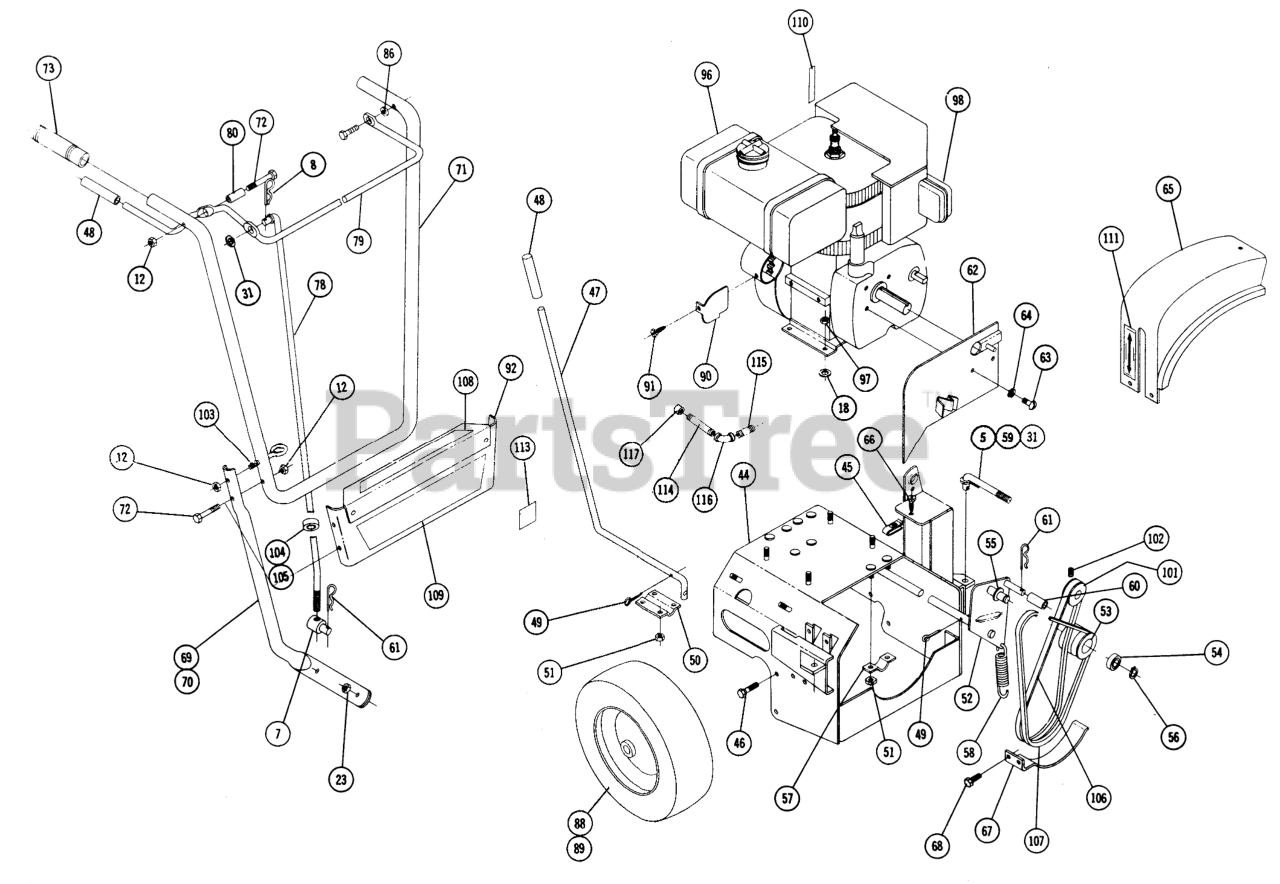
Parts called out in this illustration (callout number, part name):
1	Ass-y Rotor Ass-y
2	Guide-Belt
3	Hairpin
4	SPACER
5	Rod-Clamp
6	FLANGE
7	Trunnion
8	Hairpin
9	Ass-y Rotor L.H.
10	Ass-y Rotor R.H.
11	SHEAR BOLT
12	Nut-Nylok
13	Ass-y Impeller
14	SPIROL ROLL PIN
15	Ball Bearing
16	Set Screw
17	Bearing
18	Washer
19	Washer
20	Ass-y Blade-Scraper
21	Nut Whizlock 5/16-18
24	Washer
25	Ass-y Chute
26	Deflector
27	Bolt-3/8-16 x 3/4
28	Washer
29	Ass-y-Wing Nut
30	Ass-y Retainer
31	Washer
32	Bolt, 1/4-20 x 3/8
33	Pulley-8 Dia.
34	Set Scew, Sq. Head
35	Key
36	Ass-y Lever
37	Pully-Idler
38	Bolt, 3/8-16 x 1/2
39	SPRING
40	Ring-Truarc
41	Knob
42	V BELT
43	Cotter Pin
44	Ass-y-Housing
45	Speed Nut
46	Bolt Lug 3/8-16 x 5/8
47	Rod-Shift
48	GRIP
49	Cotter Pin
50	Bracket
51	Nut-Nylok
52	Ass-y-Clutch Arm
53	Pulley-Idler
54	Bearing-7/16 I.D.
55	Washer
56	EXTERNAL SNAP RING
57	Bracket
58	SPRING
59	3/8-16 E.S.
60	Spacer
61	Hairpin
62	Ass-y-Cover and Guide
63	Screw Rd. Hd. 5/16-24 x 1/2
64	Lockwasher
65	BELT COVER
66	Screw Hex Slotted #14-10 x 7/8
67	Guide Belt
68	Whizlock Screw 1/4-28 x 12
69	Handle-Lower L.H.
70	Handle-Lower R.H.
71	Handle-Upper
72	Bolt 5/16-18 x 1/2
73	HANDGRIP
74	Hanger
75	BUSHING-NYLINER
76	Bolt Carriage 5/16-18 x 1 3/8
77	Washer
78	Rod-Clutch
79	Handle-Control
80	Spacer
81	Collar-Locking
82	Rod-Chute Control
83	Sprocket-9 Tooth
84	PIN-SPIROL
85	SPRING COMPRESSION
86	Washer
87	Collar Hex
88	Ass-y Wheel R.H.
89	Ass-y Wheel L.H.
90	Cover-Starter Opening
91	Screw #10 x 1/2 Type A
92	Ass-y-Panel
93	SPHERICAL BUSHING
94	Socket-Crank Bushing
95	Bolt Hex 5/16-18
96	Ass-y-Engine 5 H.P.
97	Nut, Flange 3/8-16
98	Muffler
99	Pulley-Crankshaft
100	Key-Square
101	Pulley-Cam Shaft
102	Set Screw-Nylok
103	Eyebolt
104	Collar
105	Set Screw 1/4-20 x 1/2
106	V BELT
107	V BELT
108	Decal-Safety
109	Decal-Trailblazer
110	Decal-Throttle Control
111	Decal-Rotor Clutch
112	Decal-Caution-Snowchute
113	Decal "5"
114	Nipple 1/4 Pipe x 4
115	Nipple 1/4 Pipe x 1 1/4
116	Elbow 1/4" Pipe x 90deg.
117	Pipe Cap
118	Flange-Bearing
